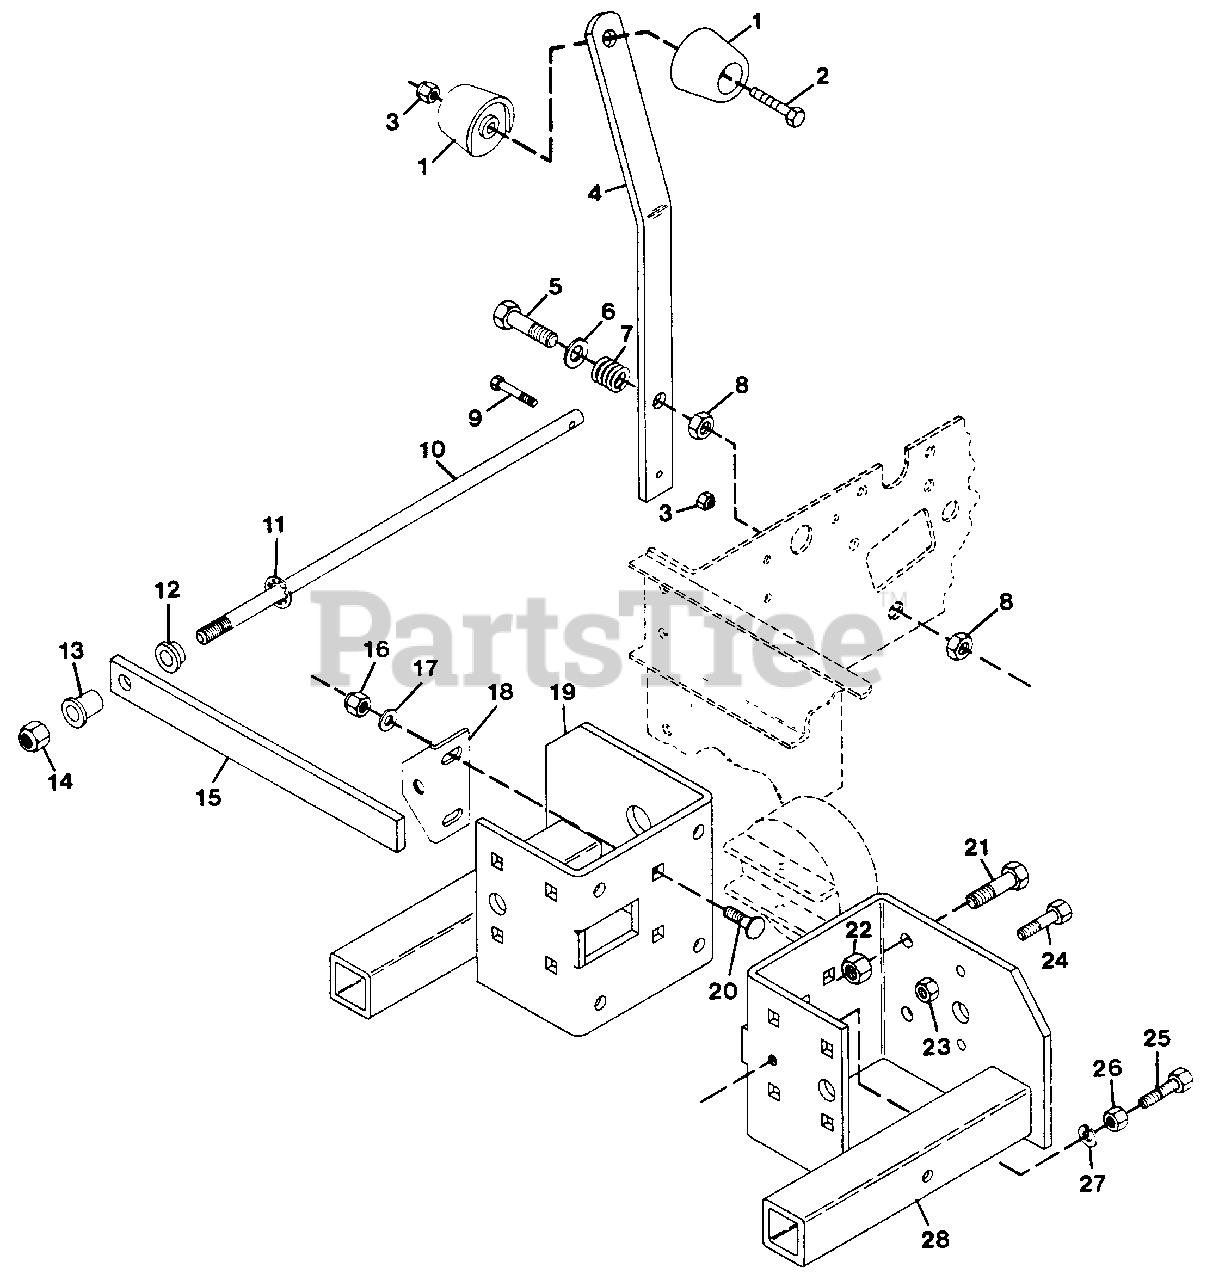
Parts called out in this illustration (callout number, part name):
1	Knob, Control
2	Bolt, Hex 1/4-20x1.50
3	Nut, Lock 1/4-20
4	Lever, PTO
5	Bolt, Hex 1/2-13x2.50
6	Washer, Flat .531x1.062x.095
7	Spring, Comp. 1x.78x338 lb/in
8	Nut, Hex 1/2-13
9	Bolt, Hex 1/4-20x1.25
10	Rod, PTO
11	Ring, Retaining
12	Bushing, .513x.750x.625
13	Bushing, Fwd-Rev Slide Rod
14	Nut, Lock 1/2-20
15	Spring, Fwd-Rev Clutch
16	Nut, Lock 5/16-18
17	Washer, Flat .344x.688x.065
18	Bracket, Interlock Switch
19	Weldment, R.H. Mower Bracket
20	Bolt, 5/16-18x.875 Rd Hd Sq Nk
21	Bolt, Hex 1/2-20x1.50
22	Nut, Rim
23	Nut, Lock 3/8-16
24	Bolt, Hex 3/8-16x1.00
25	Bolt, Hex 3/8-16x2.00
26	Nut, Jam 3/8-16 Hex
27	Washer, Lock 3/8 Reg.
28	Weldment, L.H. Mower Bracket
